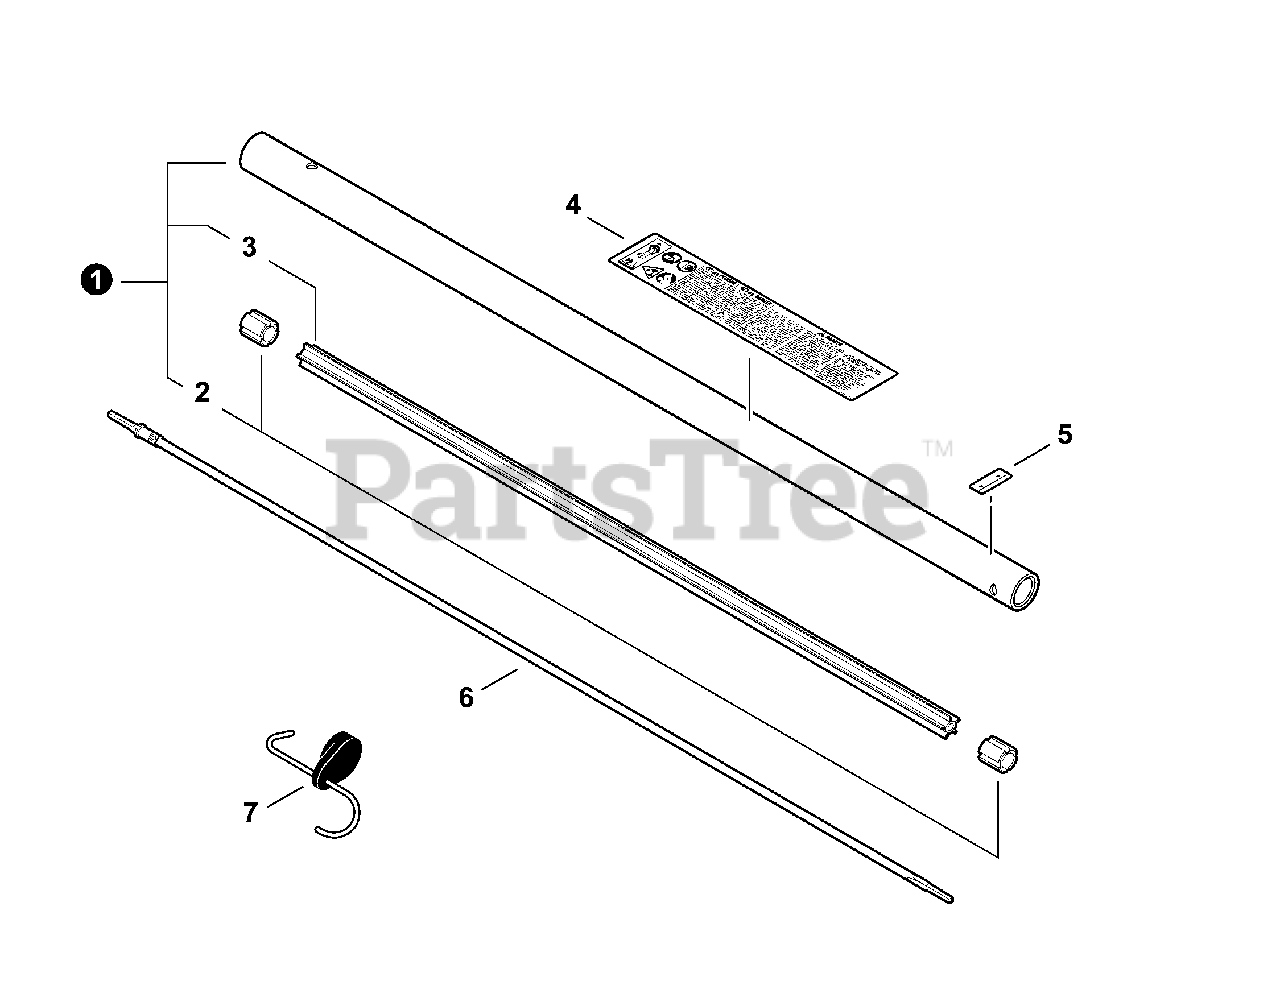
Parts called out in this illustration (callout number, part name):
1	PIPE, MAIN
3	LINER - FLEXIBLE
4	LABEL, CAUTION
5	LABEL - ALIGNMENT
6	DRIVESHAFT - FLEXIBLE
7	HANGER, ATTACHMENT
